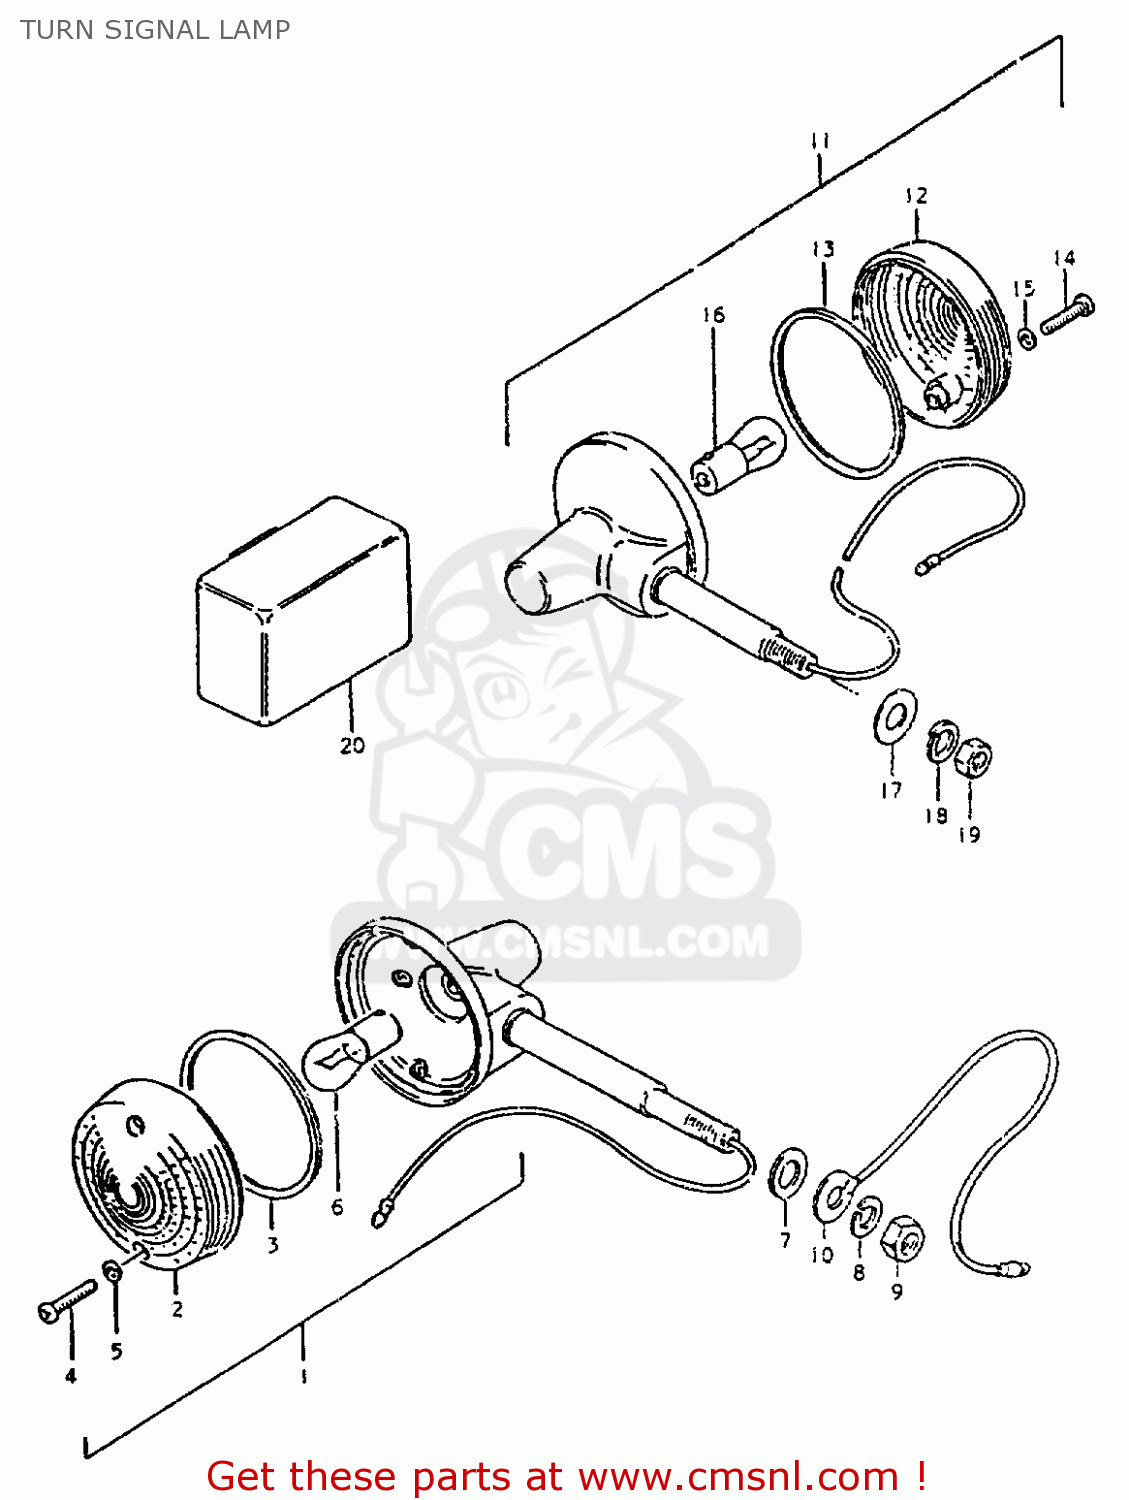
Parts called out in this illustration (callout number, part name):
1	LAMP, REAR TURN SIGNAL
2	LENS
3	GASKET (NAS)
4	SCREW
5	GASKET (NAS)
6	BULB (6V,18W)
7	WASHER
8	LOCK WASHER
9	NUT
10	WIRE
11	LAMP, REAR TURN SIGNAL
12	LENS
13	GASKET (NAS)
14	SCREW
15	GASKET (NAS)
16	BULB (6V,18W)
17	WASHER
18	LOCK WASHER
19	NUT
20	RELAY,TURN SIGNAL
